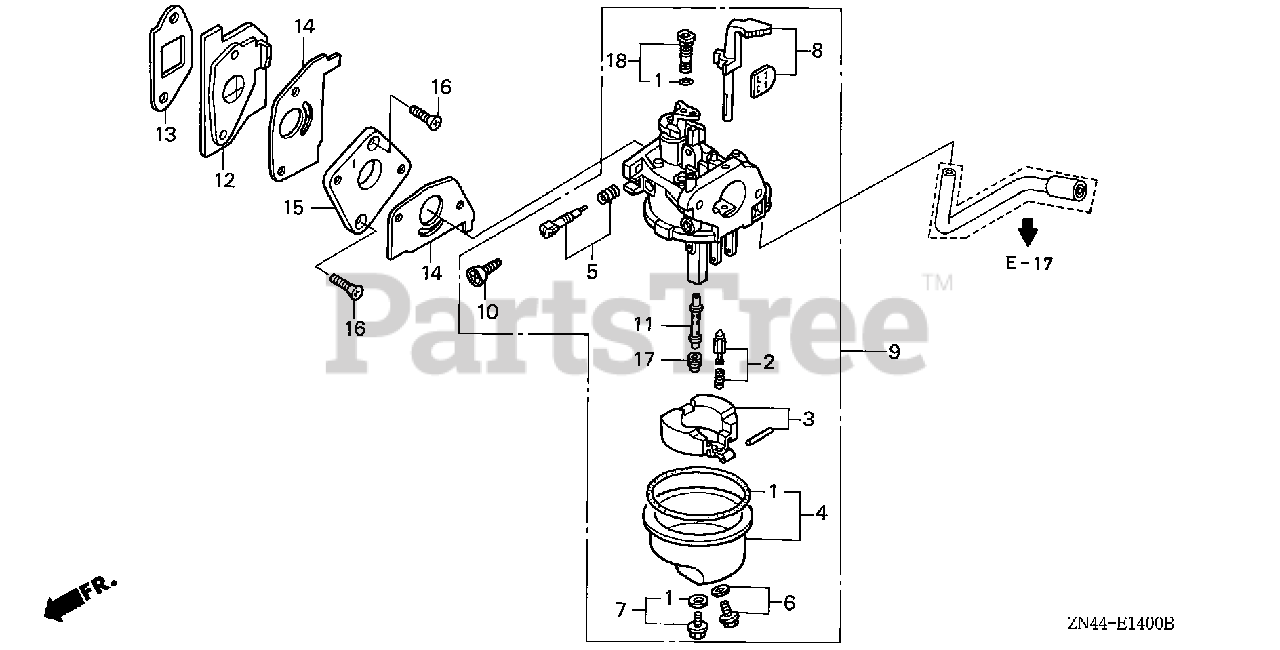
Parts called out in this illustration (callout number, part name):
1	GASKET SET
2	VALVE SET, FLOAT
3	FLOAT SET
4	CHAMBER SET, FLOAT
5	SCREW SET
6	SCREW SET, DRAIN
7	SCREW SET
8	CHOKE SET
9	CARBURETOR ASSY. (BF31D B)
10	SCREW, THROTTLE STOP
11	NOZZLE, MAIN
12	INSULATOR, CARBURETOR
13	GASKET, INSULATOR
14	GASKET, CARBURETOR
15	PLATE, CARBURETOR JOINT
16	SCREW, FLAT (5X20)
17	JET, MAIN (#50)
17	JET, MAIN (#52)
17	JET, MAIN (#55)
18	JET SET, PILOT (#35)
